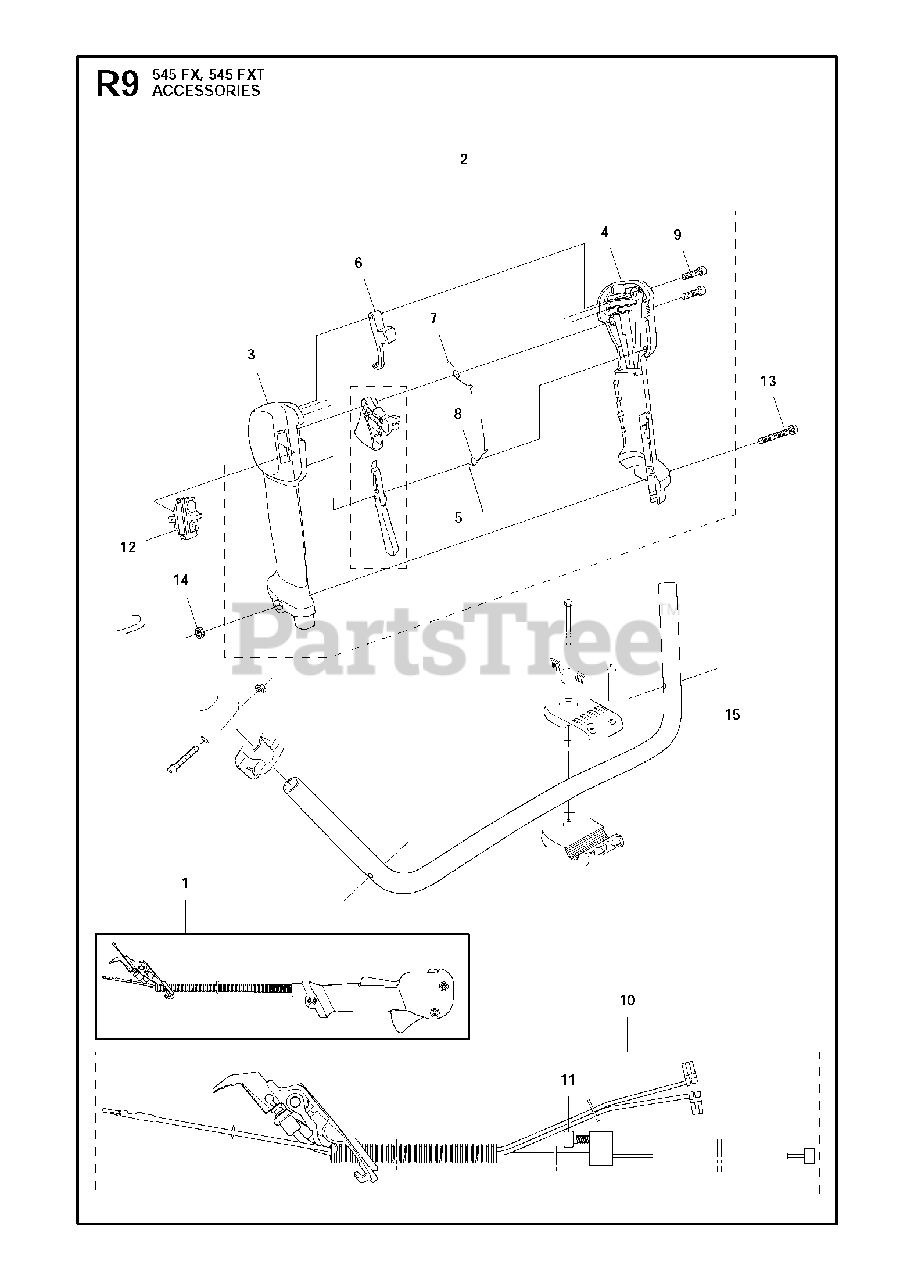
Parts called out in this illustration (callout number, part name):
1	THROTTLE HANDLE ASSY
2	THROTTLE HANDLE ASSY
3	HANDLE HALF LEFT
4	HANDLE HALF RIGHT
5	THROTTLE CONTROL
6	LOCKOUT STARTER THROTTLE
7	SPRING
8	SPRING
9	SCREW IHSCT MT4X18 10.9 ZN/FE
10	WIRING ASSY
11	SCREW
12	STOP BUTTON
13	SCREW IHSCFM
